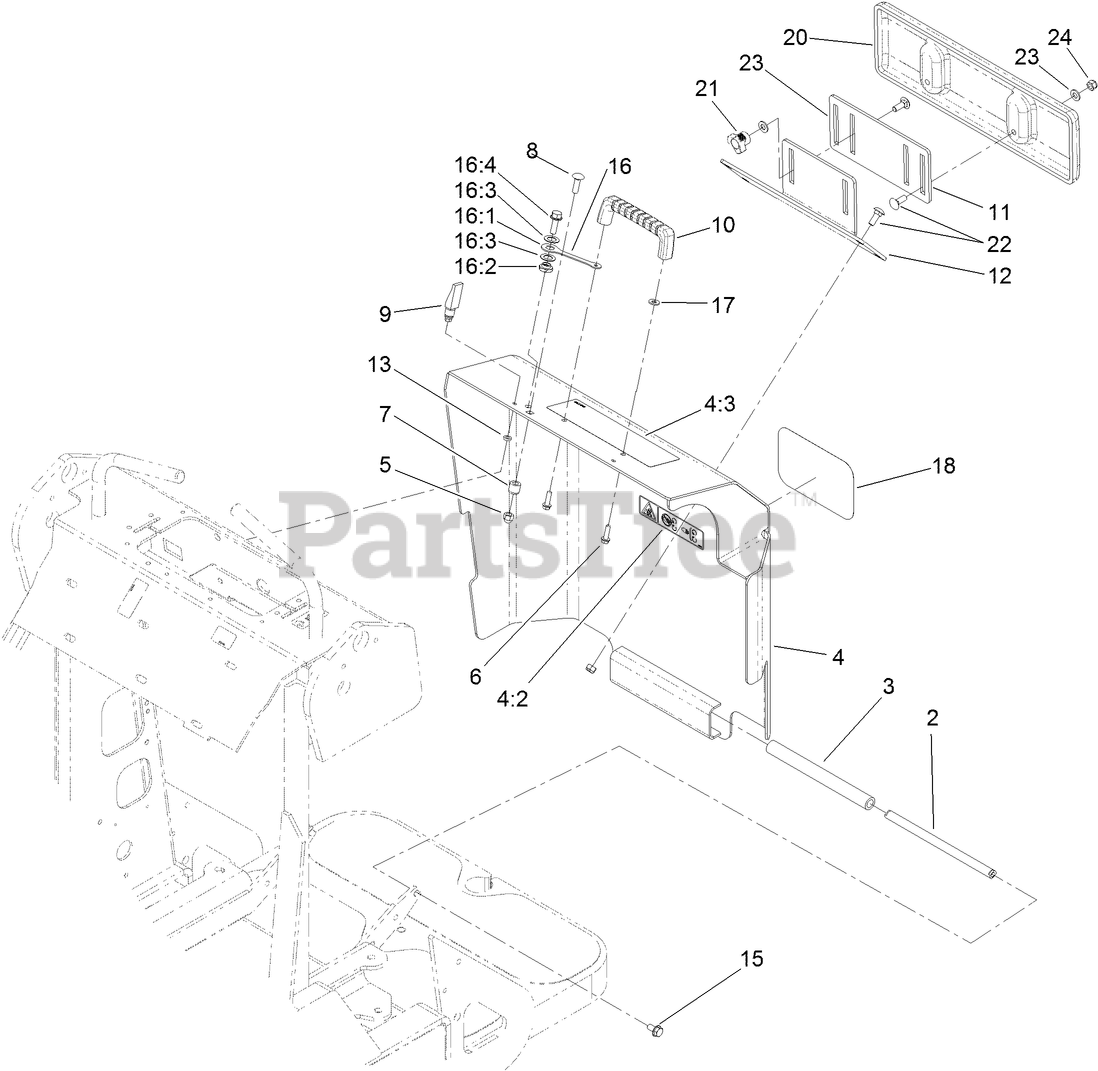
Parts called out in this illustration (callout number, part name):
2	BAR-HINGE
3	HOSE-HINGE
4	COVER ASM
4:2	DECAL-DANGER
4:3	DECAL-DANGER
5	NUT-LOCK, CAP
6	SCREW-HWH
7	SPACER-GUIDE
8	SCREW-CARR
9	LATCH-SWELL
10	HANDLE-DOOR
11	PLATE-ADJUSTING
12	BRACKET-SUPPORT, THIGH
13	WASHER
15	SCREW-HHF
16	LANYARD ASM
16:1	LANYARD-3 INCH
16:2	NUT-SHOULDER
16:3	WASHER
16:4	SCREW-HHF
17	WASHER-FLAT
18	DECAL
20	SUPPORT-THIGH
21	Knob-Adjustment
22	SCREW-CARR
23	WASHER-FLAT
24	NUT-LOCK, NI
